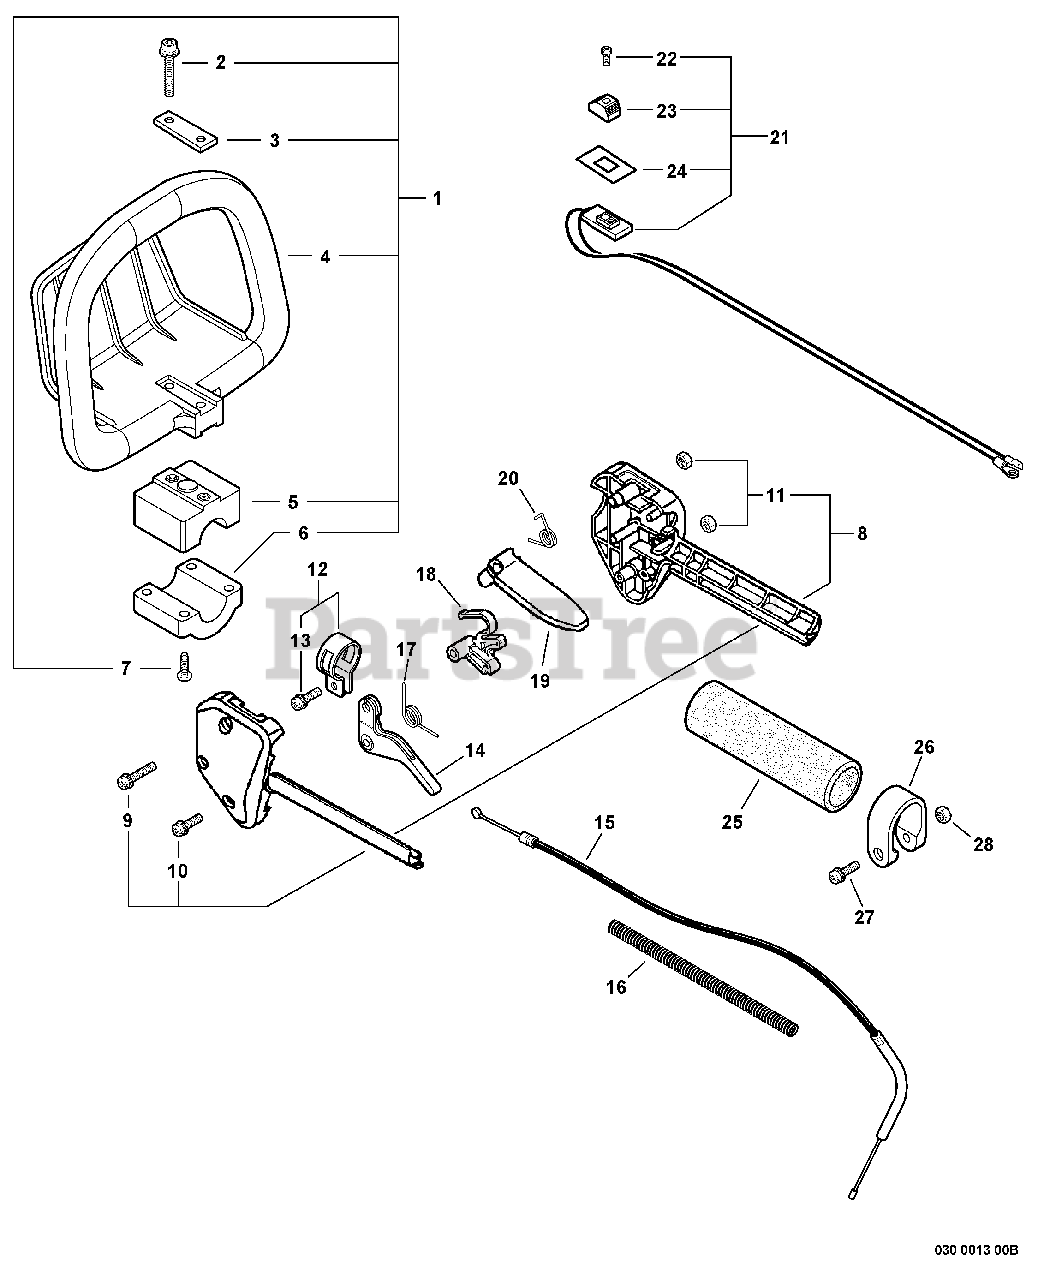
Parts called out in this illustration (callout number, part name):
1	FRONT HANDLE ASSY
2	BOLT 5×30
3	PLATE, EYE
4	HANDLE, SUPPORT
5	BRACKET, HANDLE - UPPER
6	BRACKET, HANDLE - LOWER
8	THROTTLE BRACKET SET
9	SCREW 5×35
10	SCREW 5×25
11	NUT M5
12	CLAMP KIT
13	SCREW 5×14
14	TRIGGER, THROTTLE
15	CABLE, THROTTLE
16	TUBE, PROTECTIVE - CORRUGATED
17	SPRING, TORSION
18	LOCKOUT, THROTTLE
19	LEVER, THROTTLE LOCKOUT
20	SPRING, TORSION
21	SWITCH ASSY, ON-OFF
22	SCREW 3×10
23	KNOB, SWITCH - ORANGE
24	LABEL, SWITCH
25	GRIP, HANDLE
27	SCREW 5×28
28	NUT M5
